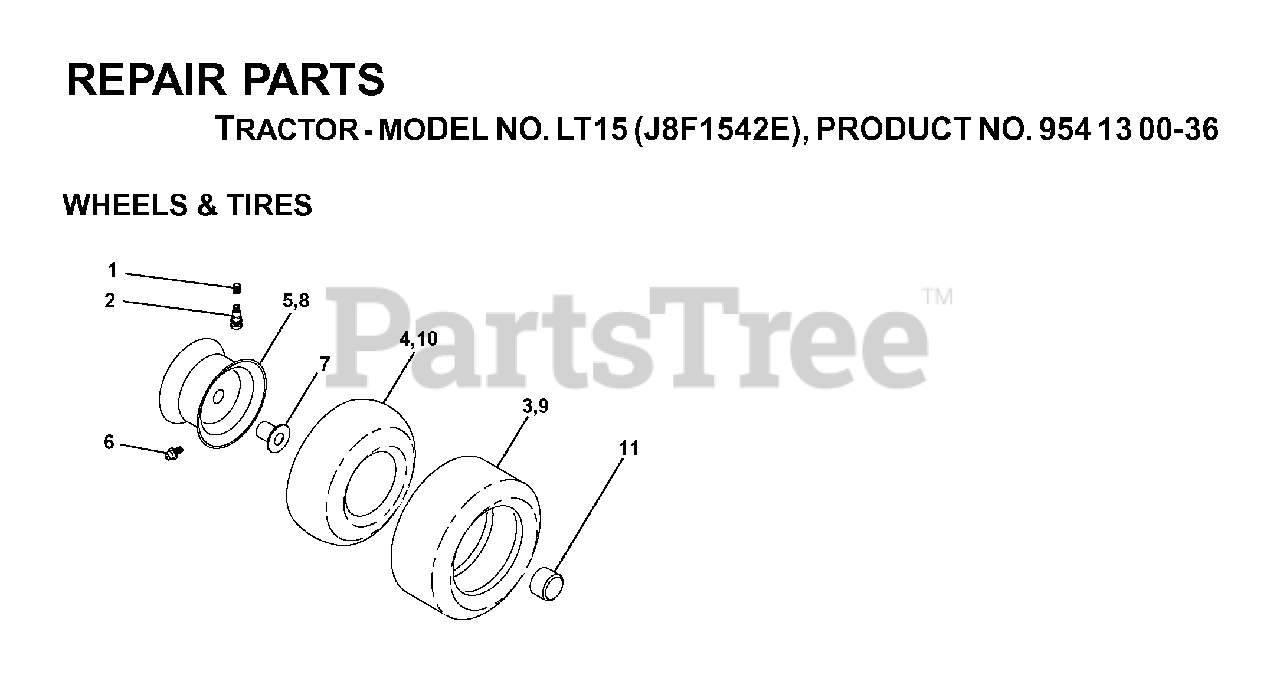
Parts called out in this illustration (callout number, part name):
1	VALVE CAP
2	VALVE STEM LT
3	TIRE HEAVY DUTY
4	TUBE.5.3/4.5/6
5	RIM ASM 6" FRONT SILVER
6	FITTING LT
7	BEARING T
8	RIM ASM 8" REAR SILVER
9	TIRE.TS.20X10-8
10	TUBE
11	CAP-HUB FRONT LT
